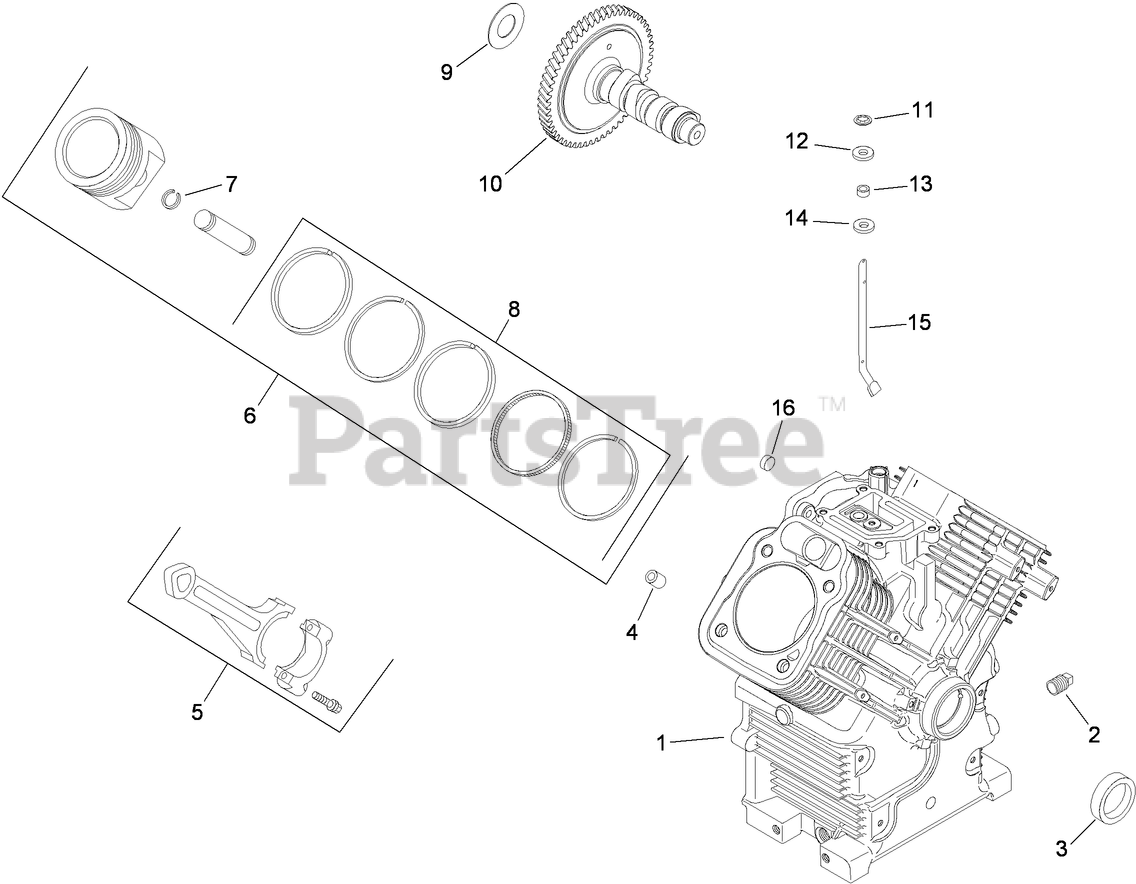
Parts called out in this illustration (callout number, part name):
1	Miniblock
2	PLUG-PIPE, SQ HD (3/8)
3	SEAL-OIL
4	Pin-Locating
5	Rod-Connecting (Standard)
5	Rod-Connecting (.25)
6	Piston w/Ring Set (STD) (Includes Ref 7, 8)
6	Piston w/Ring Set (.25) (Includes Ref 7, 8)
6	Piston w/Ring Set (.50) (Includes Ref 7, 8)
6	Piston w/Ring Set (.08) (Includes Ref 7, 8)
7	RETAINER-PIN, PISTON
8	Ring Set (STD)
8	Ring Set (.25)
8	Ring Set (.50)
9	SHIM-CAMSHAFT (RED .032)
9	SHIM-CAMSHAFT (BLACK .04)
9	SHIM-CAMSHAFT (WHITE .028)
9	SHIM-CAMSHAFT (BLUE .03)
9	SHIM-CAMSHAFT (YELLOW .034)
9	SHIM-CAMSHAFT (GREEN .036)
9	SHIM-CAMSHAFT (GRAY .038)
10	Camshaft Kit (INCLUDES 25 357 14-S)
11	RETAINER-RING
12	WASHER-FLAT (9MM)
13	SEAL-CROSS SHAFT, GOVERNOR
14	WASHER-FLAT (11/32)
15	SHAFT-CROSS, GOVERNOR
16	PLUG-CUP
